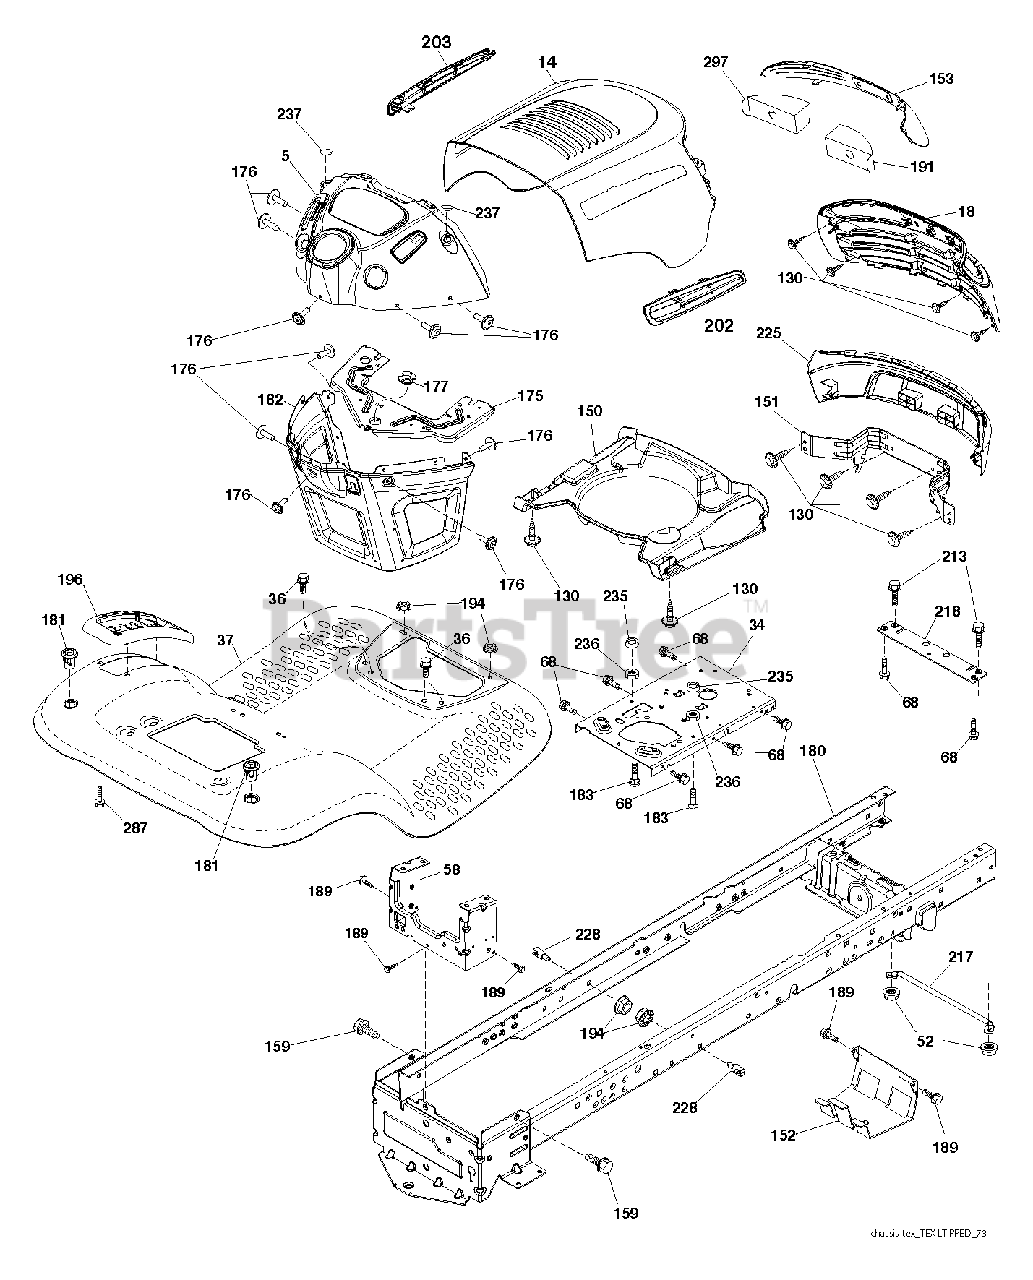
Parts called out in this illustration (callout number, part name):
5	DASH.PREDLT.CC.ICY.CK.N/SRV.BL
14	HOOD.PNT.PREDATOR.LT.TX.667
18	GRILLE.SVC.BASE.PREDATOR.LT428
34	Engine Welded Chassis Plate
36	SCREW 5/16"
37	FENDER.TLT.FS.W/NO CUPHLD.667
52	LOCKNUT
58	DRAWBAR UPPER 2PC SMALL FENDER
130	SCREW.#10 X 0.750.BOS THREAD
150	DUCT.AIR.PREDATOR.LT.2.36"
151	BRACKET.PIVOT.ALPHA.LT
152	SHIELD BROWNING
153	LENS.PREDATOR.LT
159	SCREW, 3/8-16X3/4
176	SCREW.#10-24X5/8.RN.QU
177	BUSHING STEERING
180	CHASS.WLDMNT.TL.12GA/2P.48/54
181	FEND/FTRST.PCH.CPH.NFW
182	DASH.LWER.PREDATOR/HUSQ.LT
183	BOLT.5/16-18X1-1/4 FULL THD
189	SCREW
191	INSERT.REFLECT.PREDATOR.LT.RH
194	NUT LOCK HEX FLANGE 5/16-18
196	CONSOLE.ASM.DECKLFT.BL/RBT.TLT
203	VENT.SIDE.PRED.LT.LH.JONSERED
213	BOLT
217	ROD.PIVOT.HOOD
218	X-PIECE.HOOD.STOP.NON/
225	BUMPER.GRILLE.PRED.LT.JONS.505
228	STUD.FASTNER.W/ANTI-ROTATE
235	SPACER FENDER
236	NUT.CENTERLOCK.5/16-
237	PLUG.MOUNT.CARGO.BLK
297	REFLECTOR.INSERT.PRED.LH.LT
